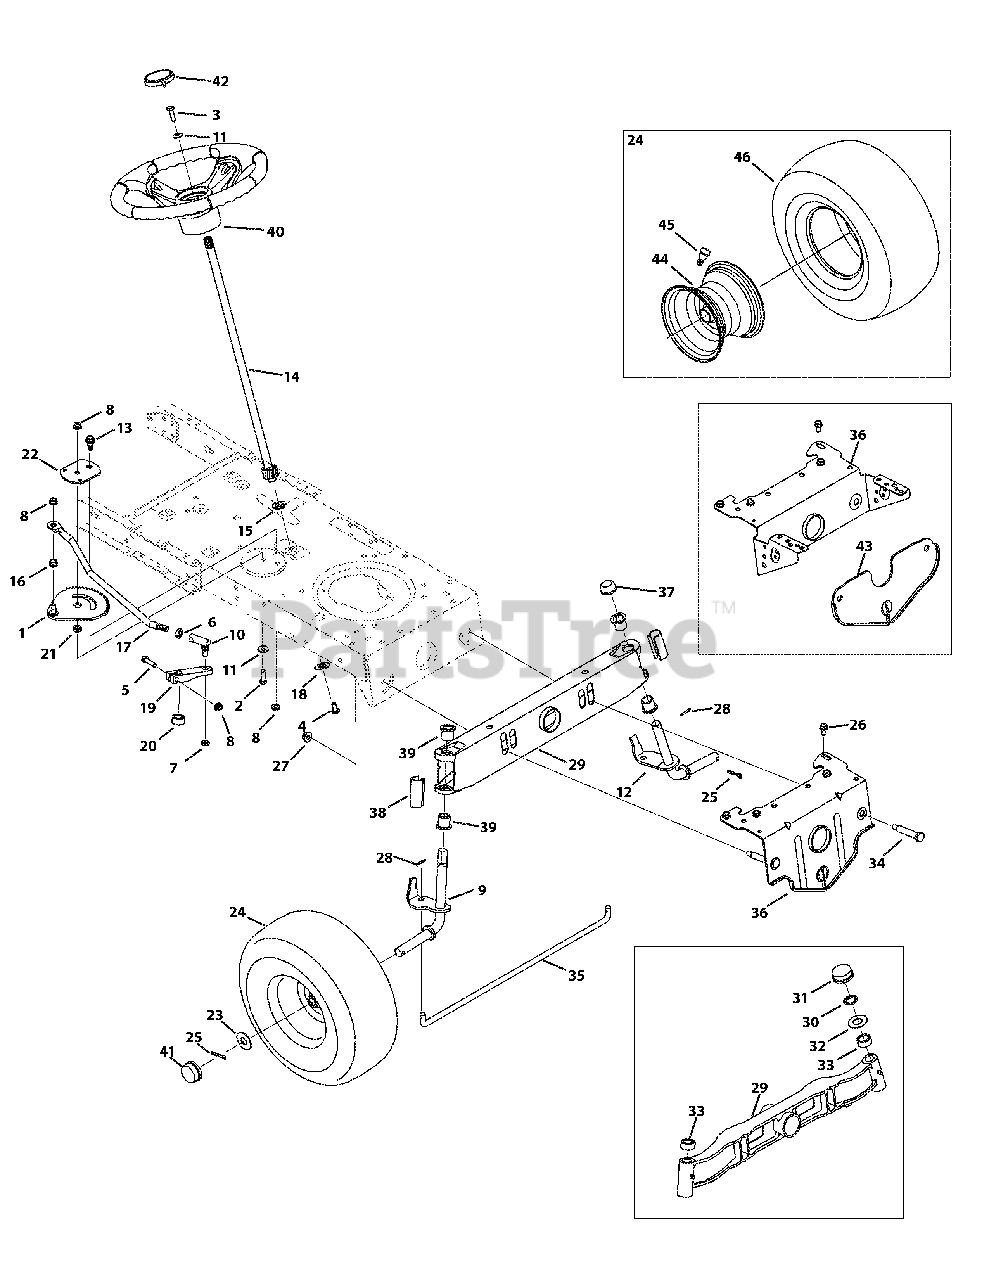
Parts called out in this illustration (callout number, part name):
1	Front Steering Gear Assembly
2	Hex Screw, 5/16-18 x 1.00
3	Hex Screw, 5/16-18 x 1.00, Lock
4	Machine Screw, 5/16-18 x .750
5	Hex Screw, 5/16-18 x 1.75
6	Jam Nut, 7/16-20
7	Jamlock Nut, 3/8-24
8	Flangelock Nut, 5/16-18
9	Front RH Axle
9	46" Front RH Axle
10	Ball Joint, 7/16-20
11	Bell Washer, .340 x .872 x .060
12	Front LH Axle
12	46" Front LH Axle
13	Shoulder Bolt, 5/16-18 x .435 x .350
14	Steering Shaft, 5/8 x 22.08
15	Flange Bearing, 5/8
16	Plastic Bushing, .380 ID
17	Steering Link
18	Cap, 1.25 x .16
19	Steering Block
20	Spacer, .71 x .125 x .56
21	Spacer, .322 x .625 .21
22	Gear Segment Stabilizer Plater
23	Flat Washer, .781 x 1.590
24	Wheel Assembly, 46"
24	Wheel Assembly, 42"/38" Grey
24	Wheel Assembly, 42"/38" Yellow
25	Cotter Pin, 5/32 x 1.25
26	Screw, 5/16-18 x .750
27	Flangelock Nut, 3/8-16
28	Cotter Pin, .125 x .75
29	Pivot Axle
29	Pivot Axle - Powder Black
29	Pivot Axle - Black Jack
29	Pivot Axle - Red
30	Push Nut, 3/4
31	Hub Cap
32	Flat Washer, .78 x 1.59 x .060
33	Spacer, .71 x .125 x .56
34	Shoulder Bolt, 3/8-16 x .500 x 2.38
35	Fixed Rod
36	Pivot Bar Bracket
37	Push Cap, 3/4
38	Standard Axle Cap
39	Flange Bearing, .760 x .941 x 1.0
40	Steering Wheel
41	Hub Cap
42	Sprig Cap
43	Front Deck Hanger Bracket
